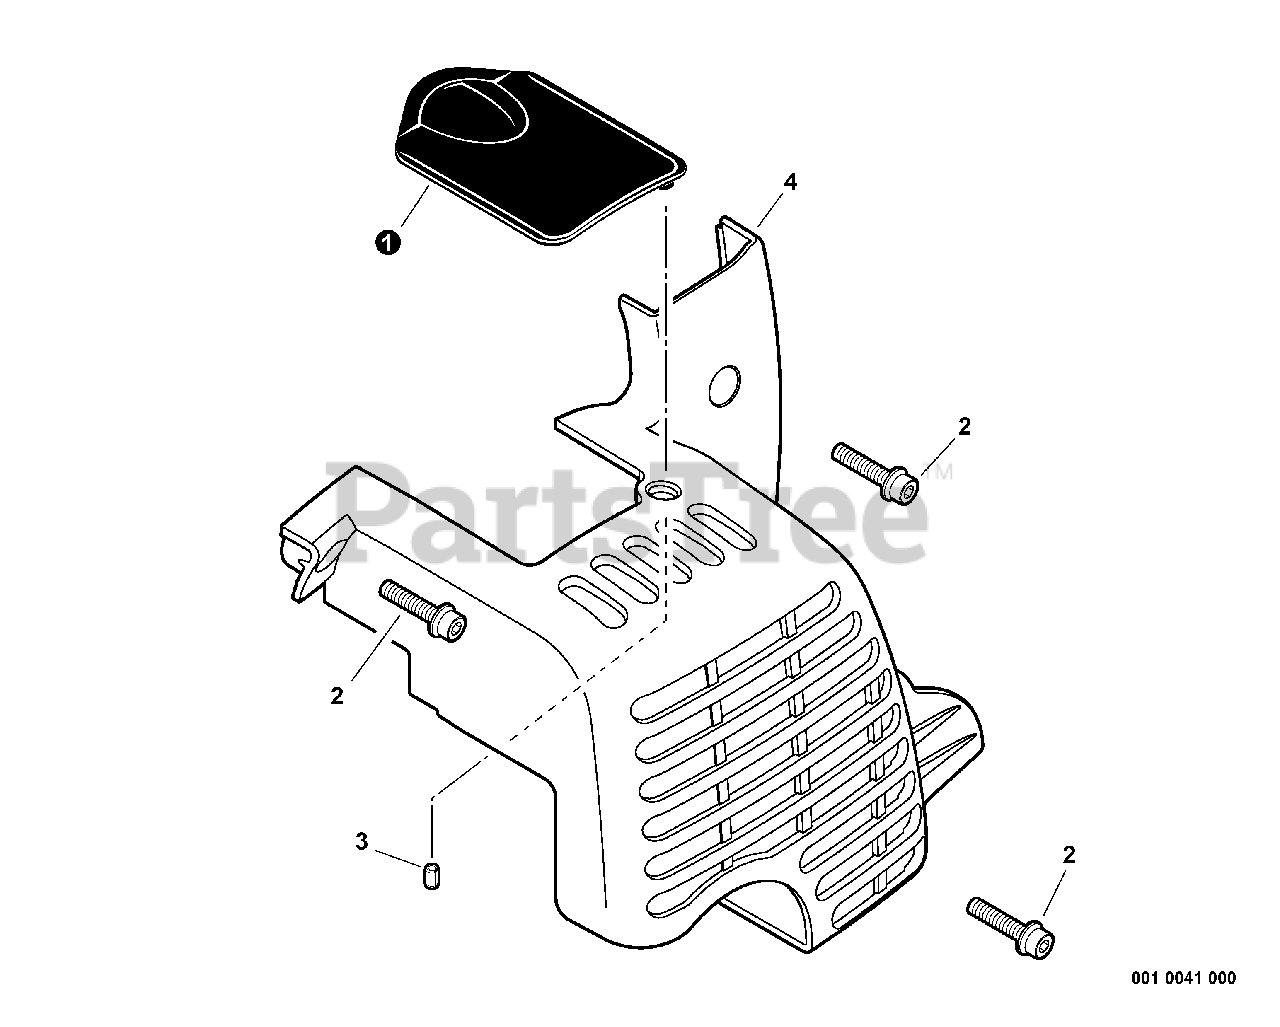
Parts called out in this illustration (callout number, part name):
1	COVER, SPARK PLUG
2	BOLT M5×20
3	PIN, SPRING 4×8
4	COVER, ENGINE
